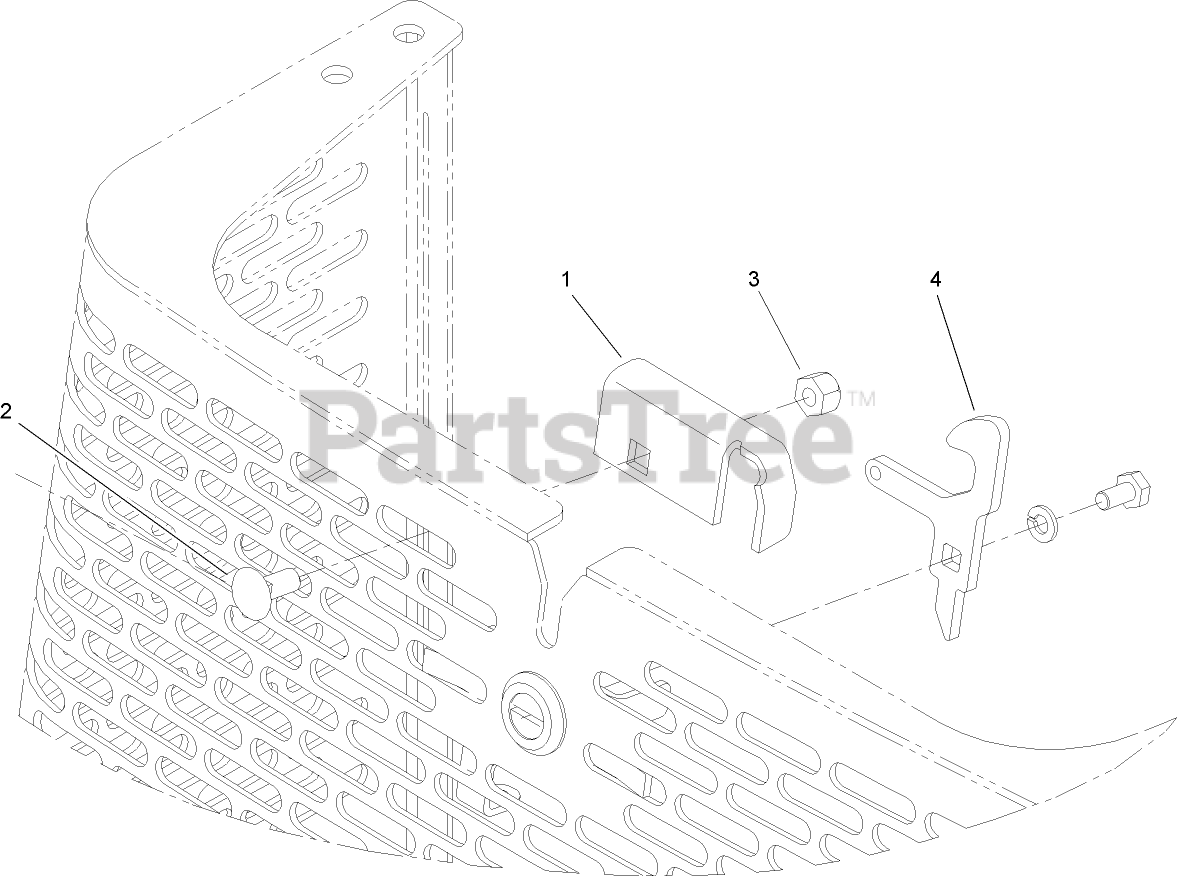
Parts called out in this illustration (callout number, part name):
1	GUIDE-LATCH
2	BOLT-CARR
3	NUT-LOCK, NI
4	CAM-LATCH
